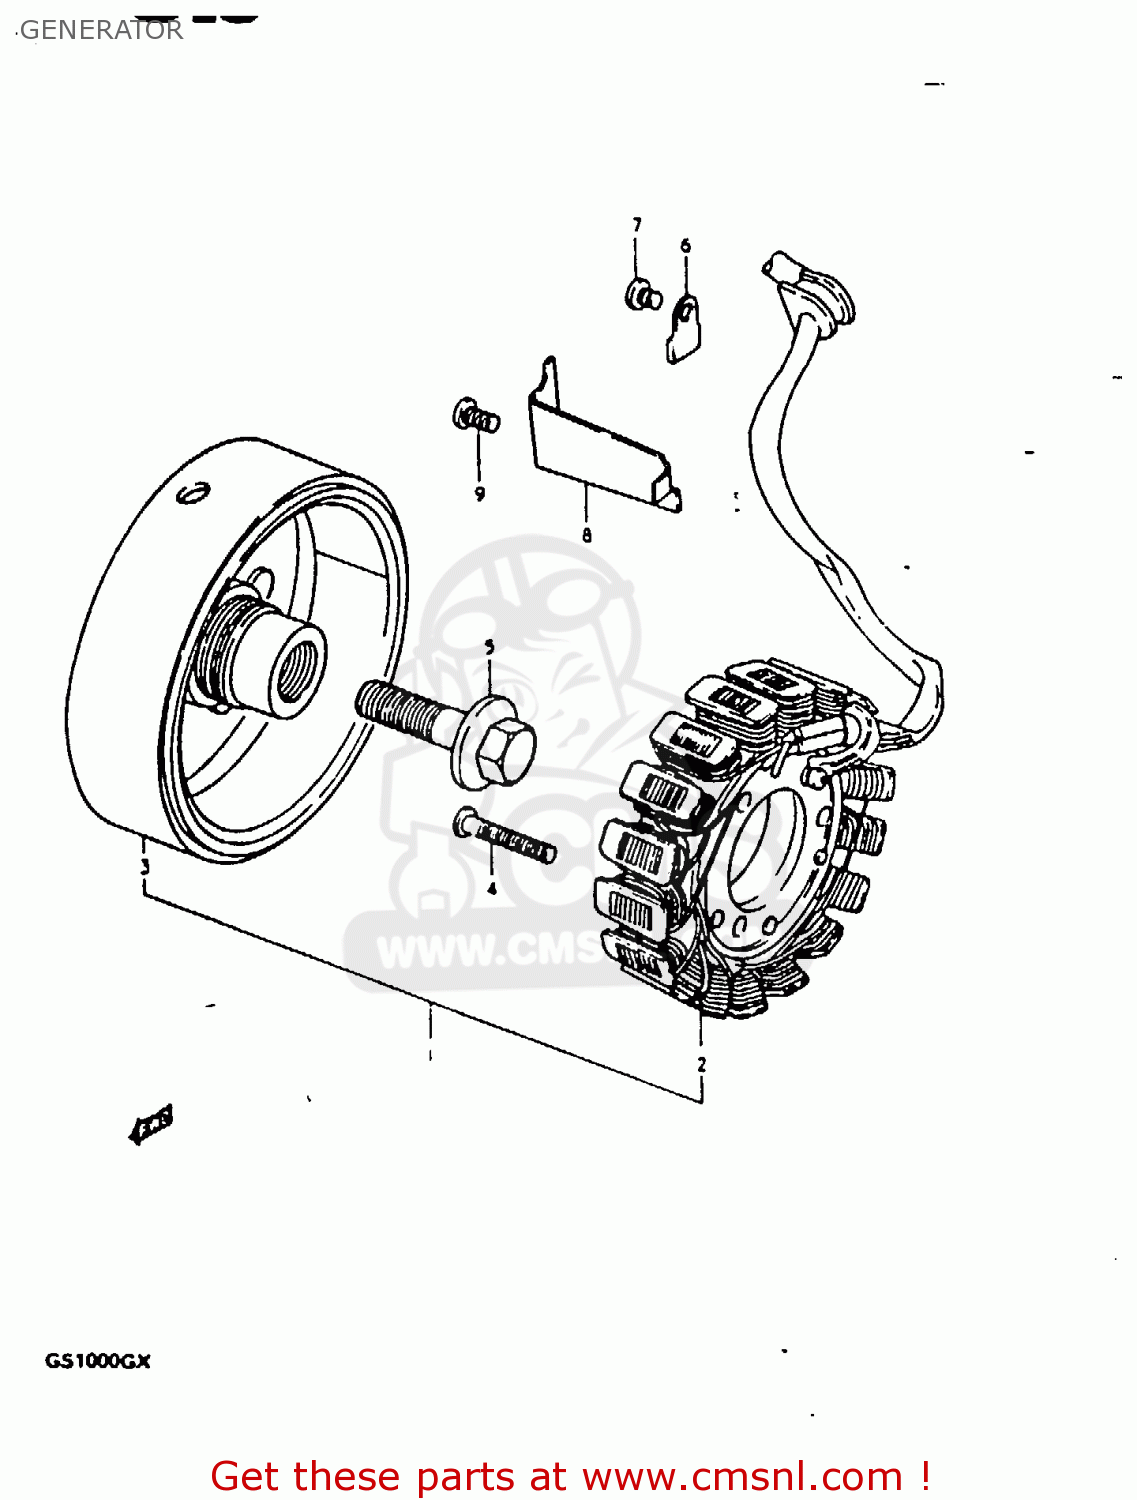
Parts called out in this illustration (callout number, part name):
1	GENERATOR ASSEMBLY
2	STATOR ASSEMBLY
3	ROTOR ASSEMBLY
4	SCREW 6X30
5	BOLT 12X45
6	CLAMP,GENERATOR LEAD WIRE
7	SCREW
8	CLAMP,GENERATOR LEAD WIRE
9	SCREW
